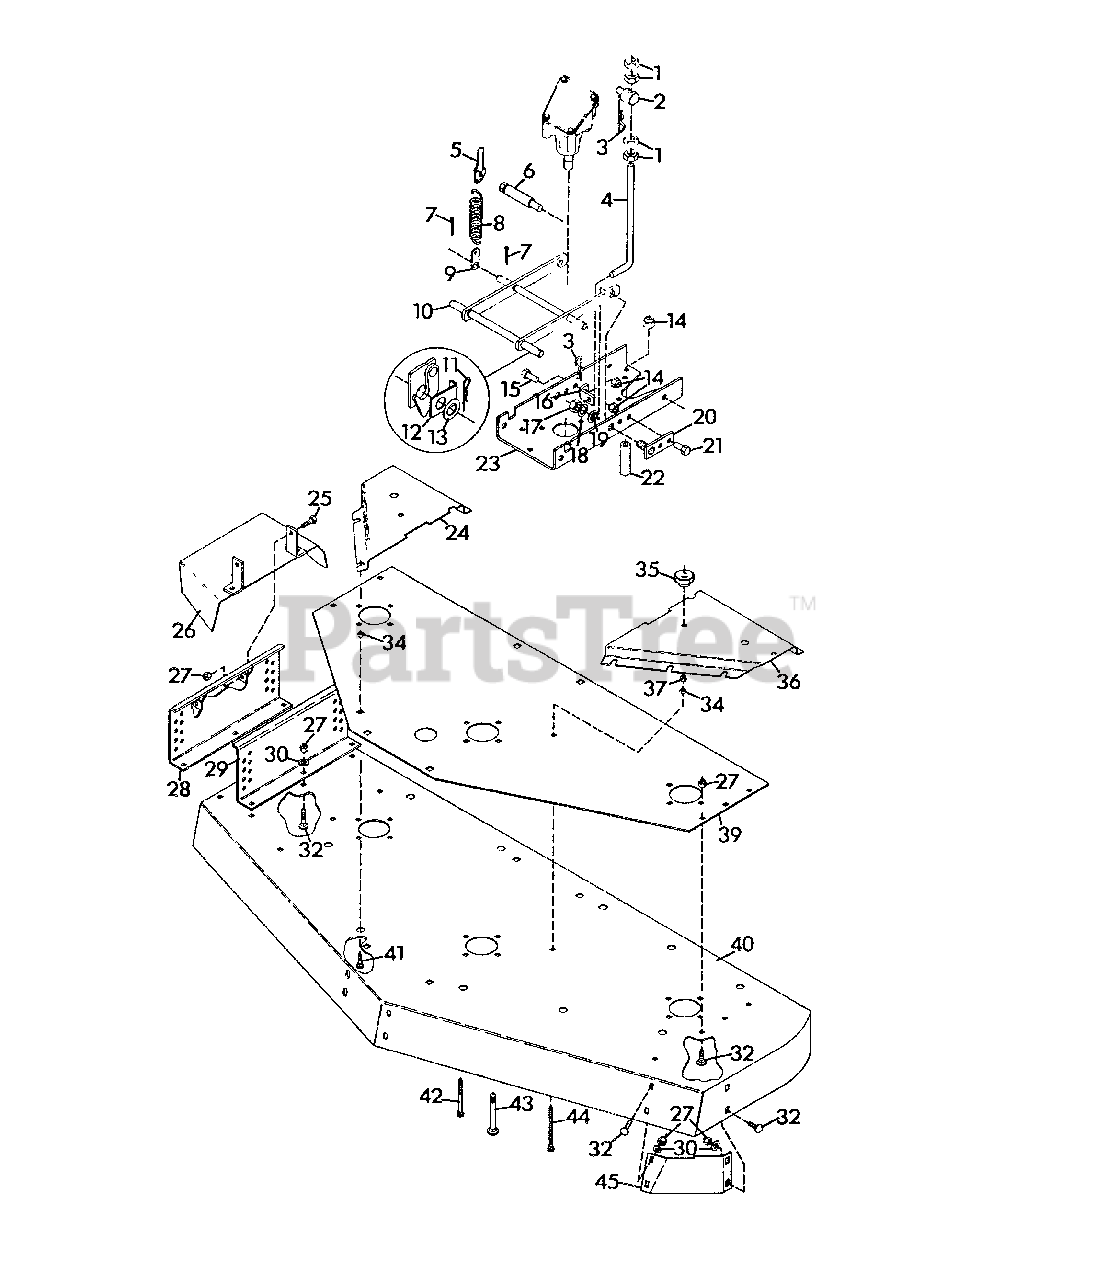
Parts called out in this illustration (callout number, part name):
1	Nut-Jam .50-13 Grade 2
2	Pivot-Mower Lift
3	Pin-Cotter .12 x 2.0
4	Rod-Lift
5	Assembly-Spring Latch Right Hand
5	Assembly-Spring Latch Left Hand
6	Latch-Pin
7	Pin-Cotter .12 x 1.25
8	Spring-Lift .244 x 1.75 x 7.6
9	Strap
10	Weldment-Pivot Arm
11	Pin-Hair-Internal .15 x 2.937
12	Keeper-Mower Pivot
13	Washer-Flat-Steel .813 x 1.370 x .100
14	Nut-Locking-Nylon .50-13 Grade 5
15	Bolt-Hex .50-13 x 1.75
16	Bracket-Lift
17	Nut-Locking .750-10
18	Washer-Hardened-Thrust .758 x 1.23 x .031
19	Bushing-Flange .762 x 1.0 x .580 x 1.48
20	Weldment-Pivot Anchor
21	Bolt-Hex .50-13 x 1.50 Grade 5
22	Spacer .562 x .855 x 2.18
23	Plate-Support
24	Cover-Belt Right Hand
25	Bolt-Hex .38-16 x 1.25 Grade 5
26	Weldment-Discharge Chute
27	Nut-Locking-Nylon .375-16 Grade 2
28	Weldment-60" Hanger
29	Hanger-Left Hand
30	Washer-Flat-Steel .406 x .812 x .065
32	Bolt-Round Head Square Neck .38-16 x 1.0
34	Nut-Locking-Center .50-20
35	Knob
36	Cover-Belt Left Hand
37	Nut-Locking-Nylon .312-18 Grade 2
39	Plate-Support
40	Weldment-60" Mower
41	Bolt-Round Head Square Neck .31-18 x 1.0
42	Bolt-Round Head Square Neck .31-18 x 3.5
43	Bolt-Round Head Square Neck .50-16 x 3.50
44	Bolt-Round Head Square Neck .31-18 x 4.0
45	Baffle-Front
